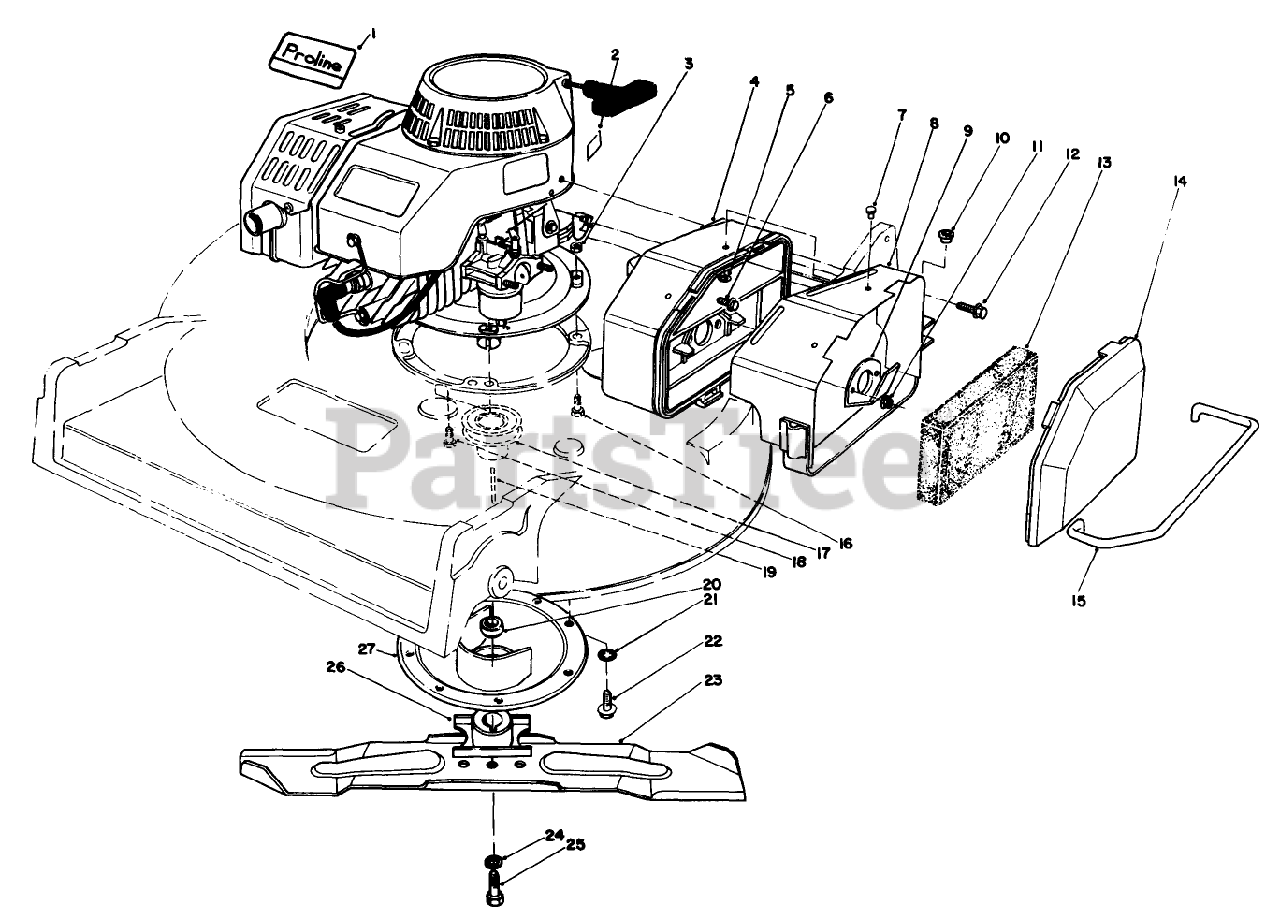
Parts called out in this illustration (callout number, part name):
1	DECAL - PROLINE
2	DECAL - FUEL
3	NUT-JAM
4	AIR CLEANER ASM
5	WASHER-FLAT
7	RIVET-POP
9	SPIT BACK DEFLECTOR
12	SCREW-HHF
13	FILTER
15	AIR CLEANER GUARD*
16	SCREW-HH
17	PULLEY-DRIVER
18	SCREW-HH
19	KEY-SQUARE
20	SPACER-BLADE RETAINER
21	WASHER-LOCK, INTERNAL
22	SCREW-HWHTF
24	WASHER-LOCK
25	SCREW-BLADE
